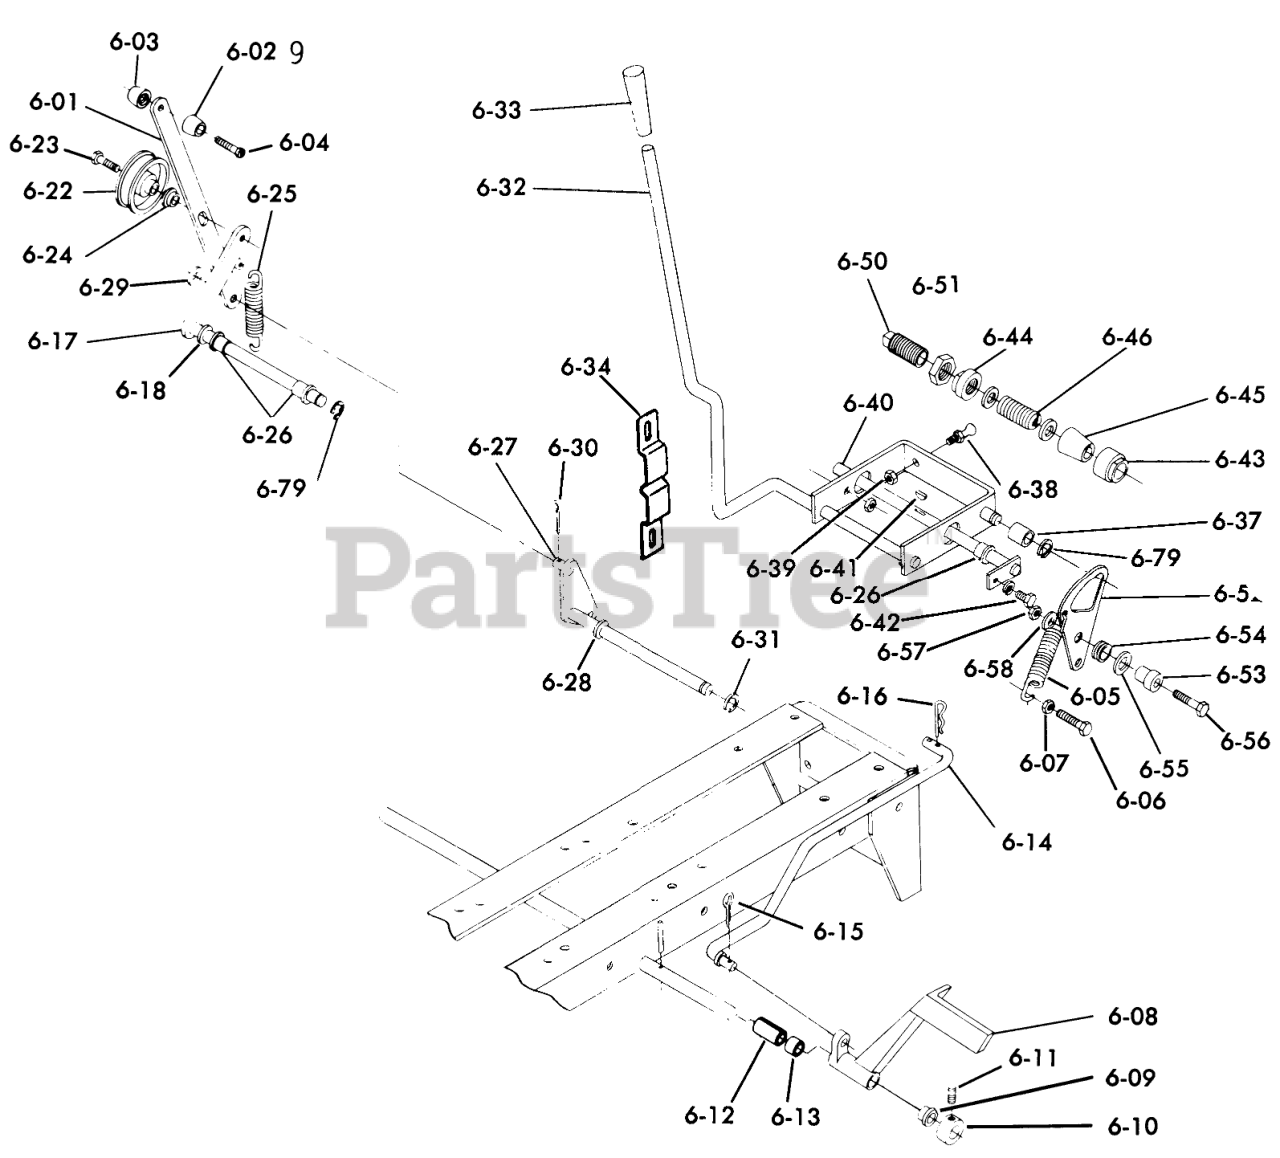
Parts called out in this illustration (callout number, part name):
6-01	HANDLE R (NS)
6-02	KNOB
6-03	KNOB
6-04	Machine Screw
6-05	Spring
6-06	Bolt
6-07	Nut
6-08	PEDAL R
6-09	BUSHING
6-10	Collar
6-11	SCREW-SET
6-12	SPACER
6-13	Spacer
6-14	Gasket
6-17	Idler Arm
6-18	Washer
6-18	Bolt
6-18	Nut
6-22	Idler Pulley
6-23	HEX HD CAP SCREW
6-24	SPACER-BRAKE LINK
6-25	SPRING-EXTENSION
6-26	BUSHING-FLANGED
6-27	ever Brake
6-28	Washer
6-29	Washer
6-30	Cotter Pin
6-31	E Ring
6-32	Cam Control
6-33	KNOB
6-34	SPRING-DETENT
6-34	WASHER 5/16 SAE
6-34	SCREW
6-37	BEARING-CAM RETURN
6-38	PIN
6-39	Nut
6-40	Cam Pivot Rod
6-41	WOODRUFF KEY
6-42	SCREW
6-43	FRICTION COLLAR
6-44	COLLAR BRKT PIVOT
6-45	FRICTION CONE
6-46	SPRING FRICTION
6-47	BUSHING-FLANGED
6-47	Washer
6-50	Collar Friction
6-52	Cam Plate
6-53	Spacer
6-54	NYLINER BUSHING
6-55	SHIM-WASHER
6-56	Bolt
6-57	Nut
6-58	Washer
